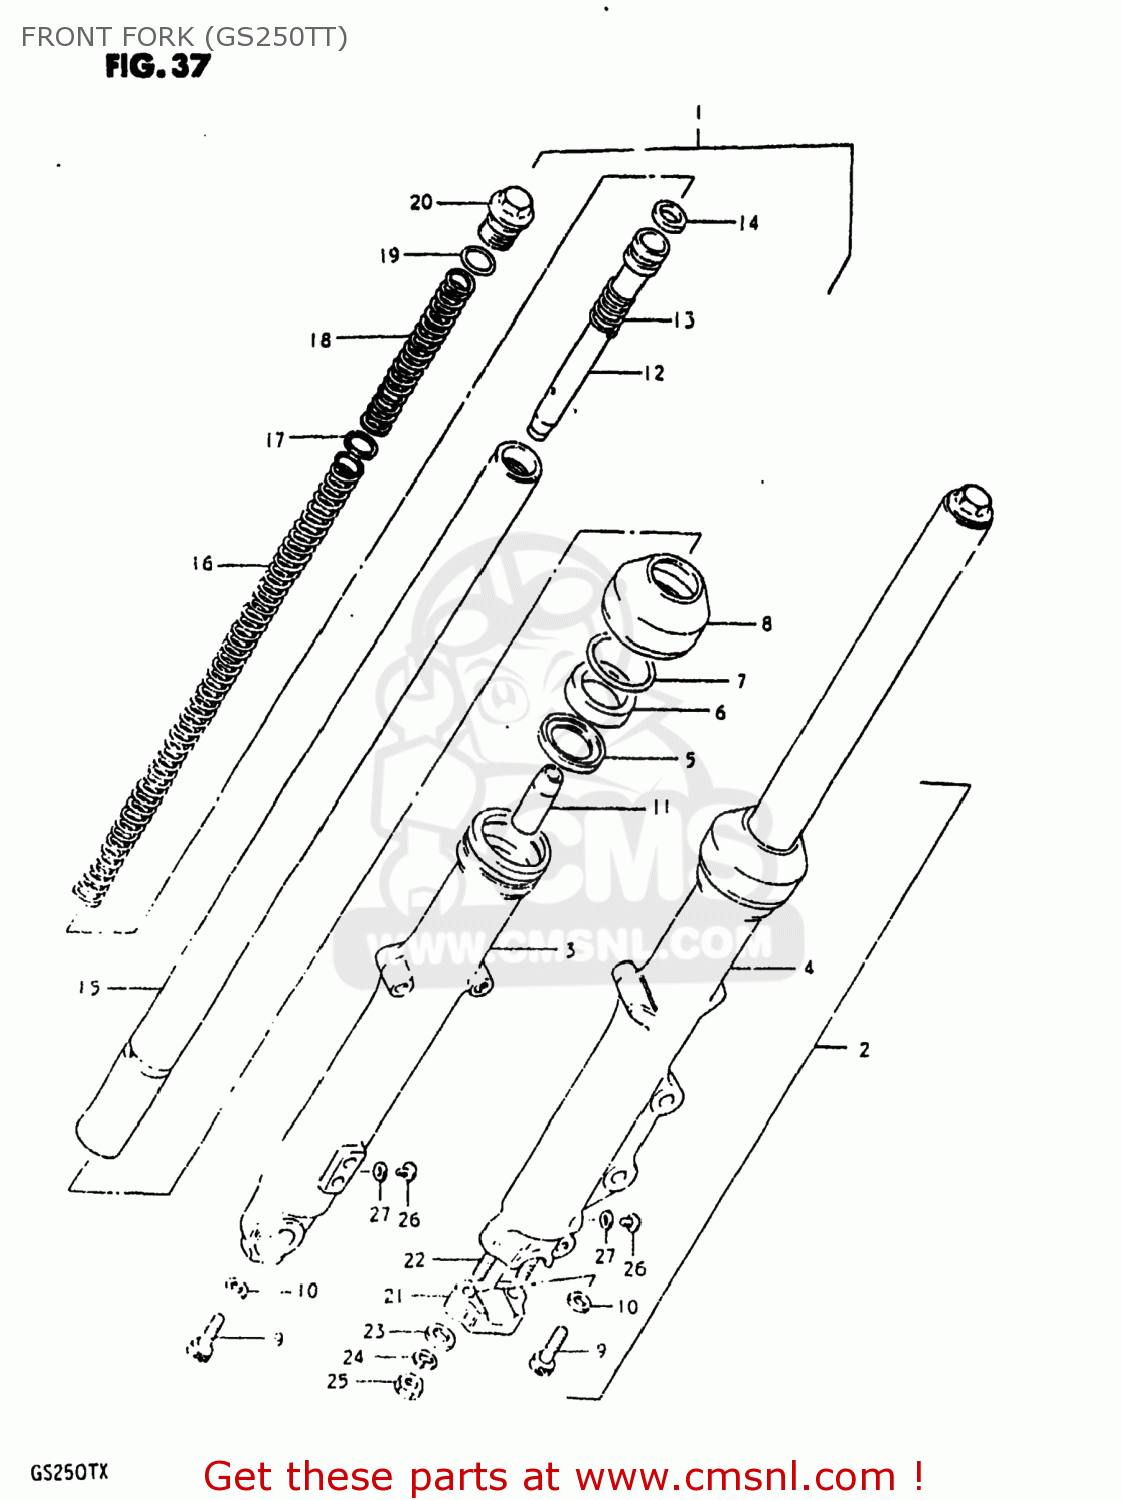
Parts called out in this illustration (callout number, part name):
1	DAMPER ASSEMBLY,FRONT FORK
2	DAMPER ASSEMBLY,LEFT
3	TUBE,FORK,OUTER,RIGHT
4	TUBE,FORK,LEFT,OUTER
5	SPACER,OIL SEAL
6	OIL SEAL,FRONT FORK
7	CIRCLIP,FORK OIL SEAL
8	BOOT
9	BOLT(8X27)
10	GASKET (NAS)
11	PIECE,OIL LOCK
12	CYLINDER,FRONT FORK
13	SPRING,REBOUND
14	RING,PISTON
15	TUBE,INNER
16	SPRING
17	SEAT,SPRING
18	SPRING,FRONT FORK
19	O RING
20	BOLT
21	HOLDER,AXLE
22	STUD 8X25
23	WASHER
24	LOCK WASHER
25	NUT (8MM)
26	SCREW 4X6
27	GASKET (NAS)
